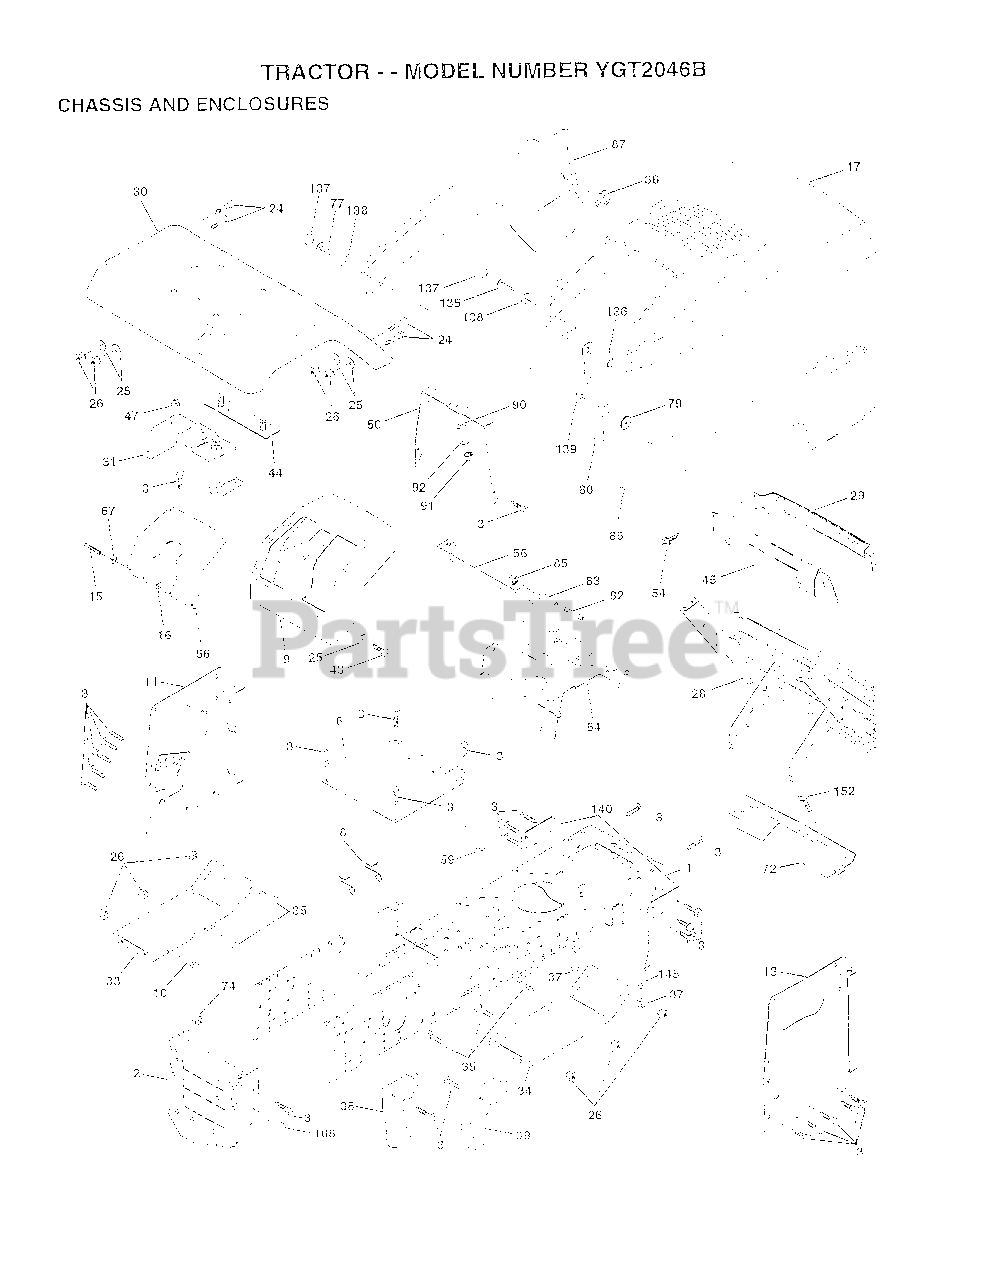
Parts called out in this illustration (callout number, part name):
3	SCREW
6	SADDLE
8	"CLIP,INSULATOR"
9	DASHBOARD BLACK
11	PANEL.DASH.LH.PNT
13	PANEL.DASH.RH.PNT
15	SCREW
17	"HOOD, YARD PRO"
24	BOLT
25	WASHER
26	NUT
28	GRILLE ASM PNT
29	LENS.BAR.CLEAR
30	"FENDER WS,FTK"
31	BRKT.ASM.FENDER
33	FOOTREST PNT LH
34	FOOTREST.RH.LT/GT
35	BOLT
36	PAL NUT LT
38	BRACKET ASM LH
39	BRACKET ASM RH
43	SCREW
44	STRAP ASM FENDER
45	BEZEL.ASM.
47	NUT-PUSH YT
50	DASH.SUPT.YP/HUSQ
54	SCREW.HEX.WS.HD
56	EXT DASH LTYT
64	DASH.LOWER.LT
66	"PLATE DASH,SLKSCR"
67	WASHER
77	SCREW
79	WELDNUT
80	HOOD LATCH T
82	SCREW
83	SPACER LT
86	"PANEL ASM SIDE,RH"
87	"PANEL ASM-SIDE,LH"
90	WASHER PM
92	LOCKWASHER
135	SCREW.10-24X3/8.
136	ACORN NUT RB
137	SNAP CAP LT
138	WASHER LT
139	BKT.SPT.HOOD/PANL
140	BRKT SUSPENSION
145	"ROD POVOT,CHASSIS"
152	SCREW
